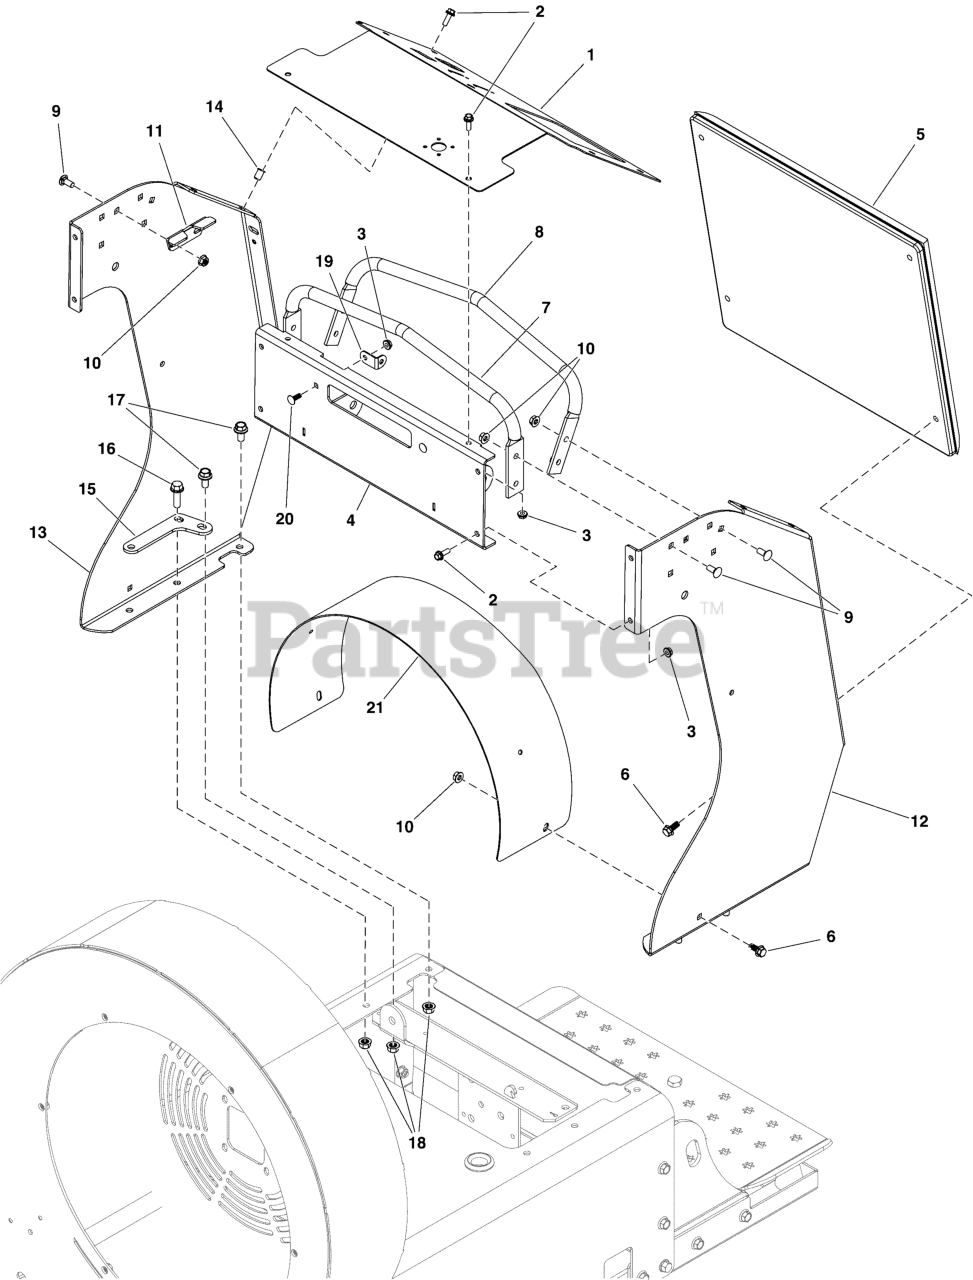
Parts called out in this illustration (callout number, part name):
1	PLATE, DASH PANEL, NEW WITH DECALS
5	PAD, KNEE
6	SCREW, 5/16-18
7	HANDLE, FRONT
8	HANDLE, REAR
9	BOLT, 5/16-18 X 3/4",
10	NUT, 5/16-18 HEX SERR
12	CONTROL, TOWER
13	CONTROL, TOWER
16	BOLT
17	BOLT
19	BRACKET, L Headlight Mount
20	BOLT, 1/4-20X.750, SQ
21	GUARD, BELT
